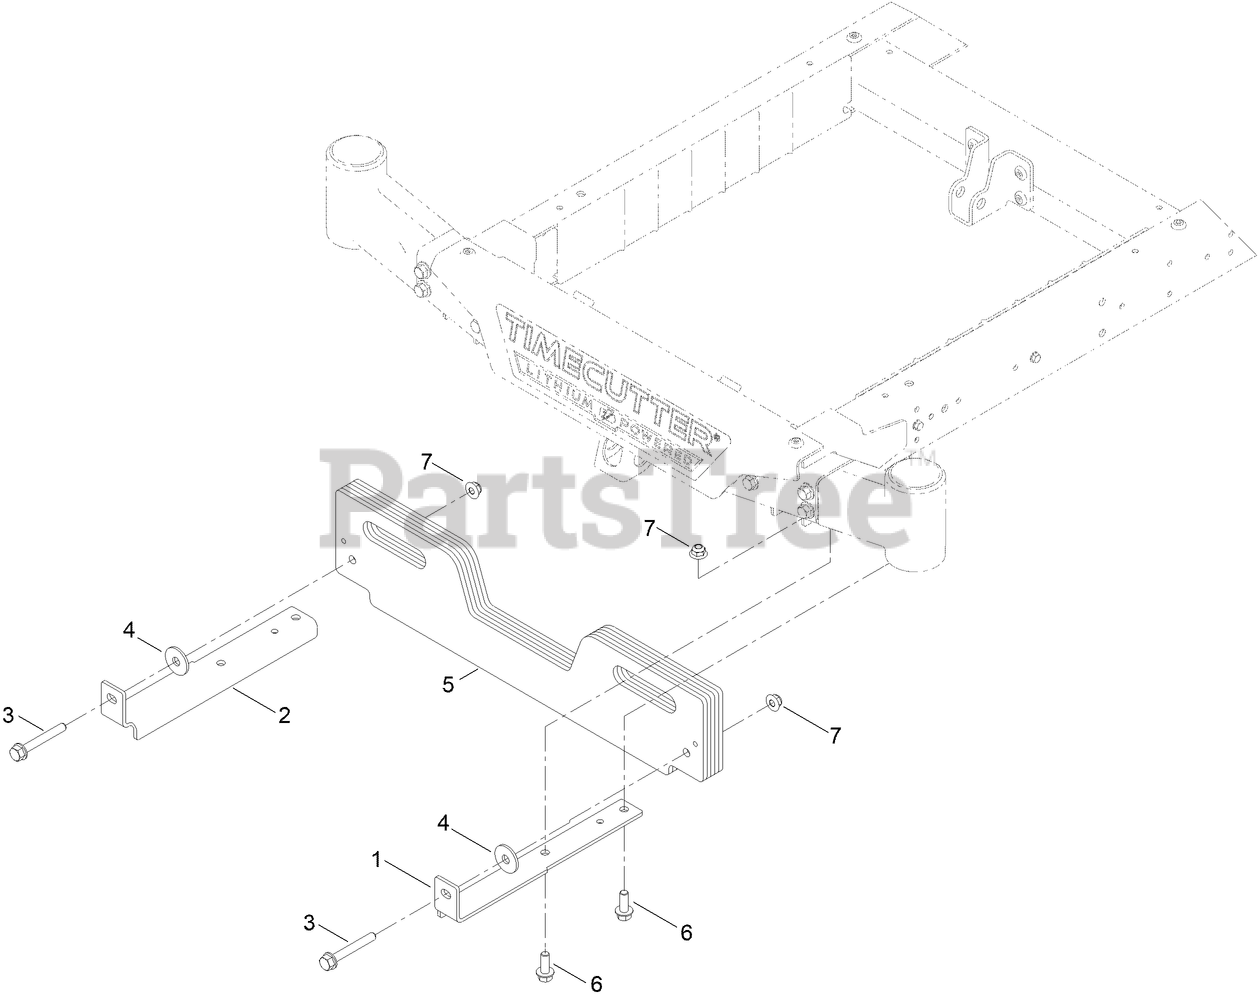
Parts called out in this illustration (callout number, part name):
1	BRACKET-WEIGHT, LH
2	BRACKET-WEIGHT, RH
3	SCREW-SPCL
4	WASHER
5	WEIGHT-BAGGER
6	SCREW-HHF
7	NUT-HF, NI
